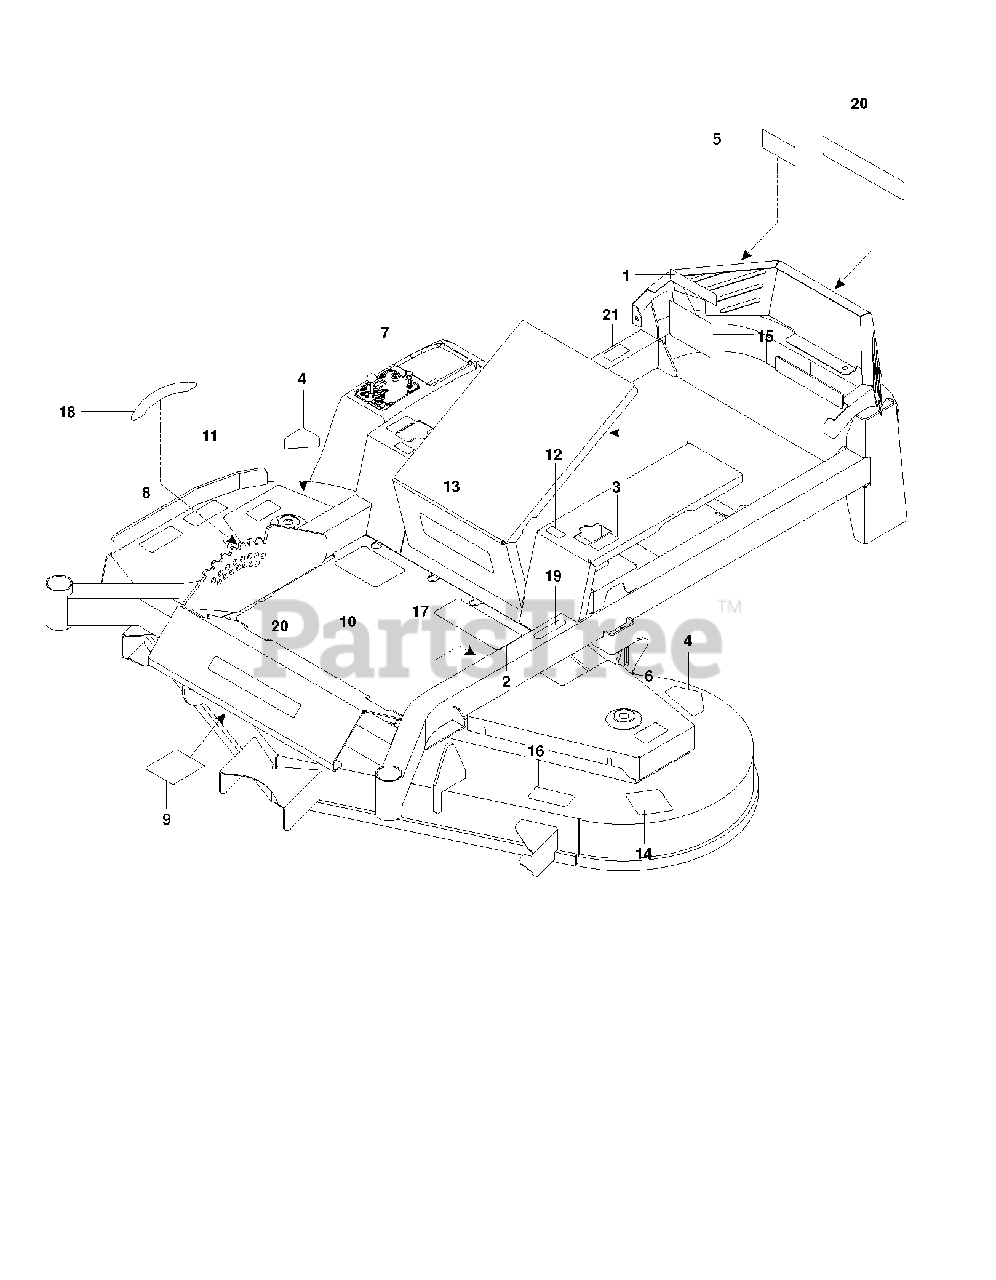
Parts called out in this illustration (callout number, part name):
2	DECAL, WARNING
3	DECAL, MOTION CONTROL
4	DECAL, CPSC
5	DECAL, BELT DRIVE
8	DECAL, EURO SEVERING
9	DECAL, BELT ROUTING
10	DECAL, WARNING
12	DECAL, TRACKING
13	DECAL, RAM ULTRA
14	DECAL, 61
15	DECAL, SERVICE
16	DECAL, TRI-FORCE
18	DECAL, HEIGHT ADJUSTMENT
19	DECAL, PARK BRAKE
21	DECAL, ECM, AUSTRALIA
